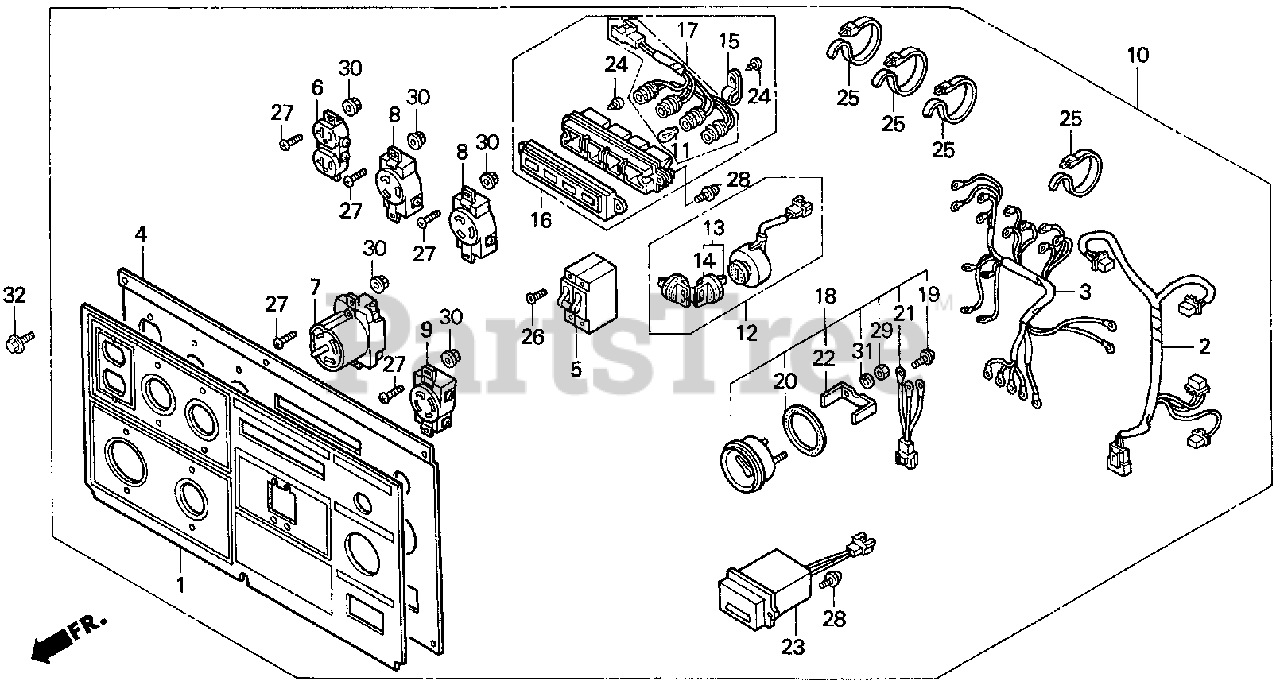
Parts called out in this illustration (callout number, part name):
1	PLATE A, CONTROL INDICATION
2	WIRE HARNESS ASSY., CONTROL (MAIN)
3	WIRE HARNESS ASSY., CONTROL (RECEPTACLE)
4	PANEL, CONTROL *B132* (JOHN BLUE)
5	BREAKER, CIRCUIT (48A)
6	RECEPTACLE (20A-125V)
6	RECEPTACLE (20A/125V)
7	RECEPTACLE (50A-125/250V)
8	RECEPTACLE (3-PRONG) (30A/125V)
9	RECEPTACLE (30A-125/250V)
10	PANEL ASSY., CONTROL *B132* (JOHN BLUE) (N/A: SEE COMPONENTS)
11	BULB, WEDGE BASE (12V1.7W) (NIPPON SEIKI)
12	SWITCH ASSY., COMBINATION
13	KEY ASSY., COMBINATION SWITCH
14	CAP, COMBINATION SWITCH KEY
16	INDICATOR ASSY.
18	METER ASSY., FUEL
19	SCREW-WASHER (3X22)
21	WIRE ASSY.
23	METER ASSY., HOUR
24	SCREW, TAPPING (4X14)
25	TIE, CABLE
26	SCREW, PAN (3X6)
27	SCREW, PAN (4X12)
28	SCREW-WASHER (5X16)
29	NUT, HEX. (4MM)
30	NUT, FLANGE (4MM)
31	WASHER, SPRING (4MM)
32	BOLT, FLANGE (6X12)
